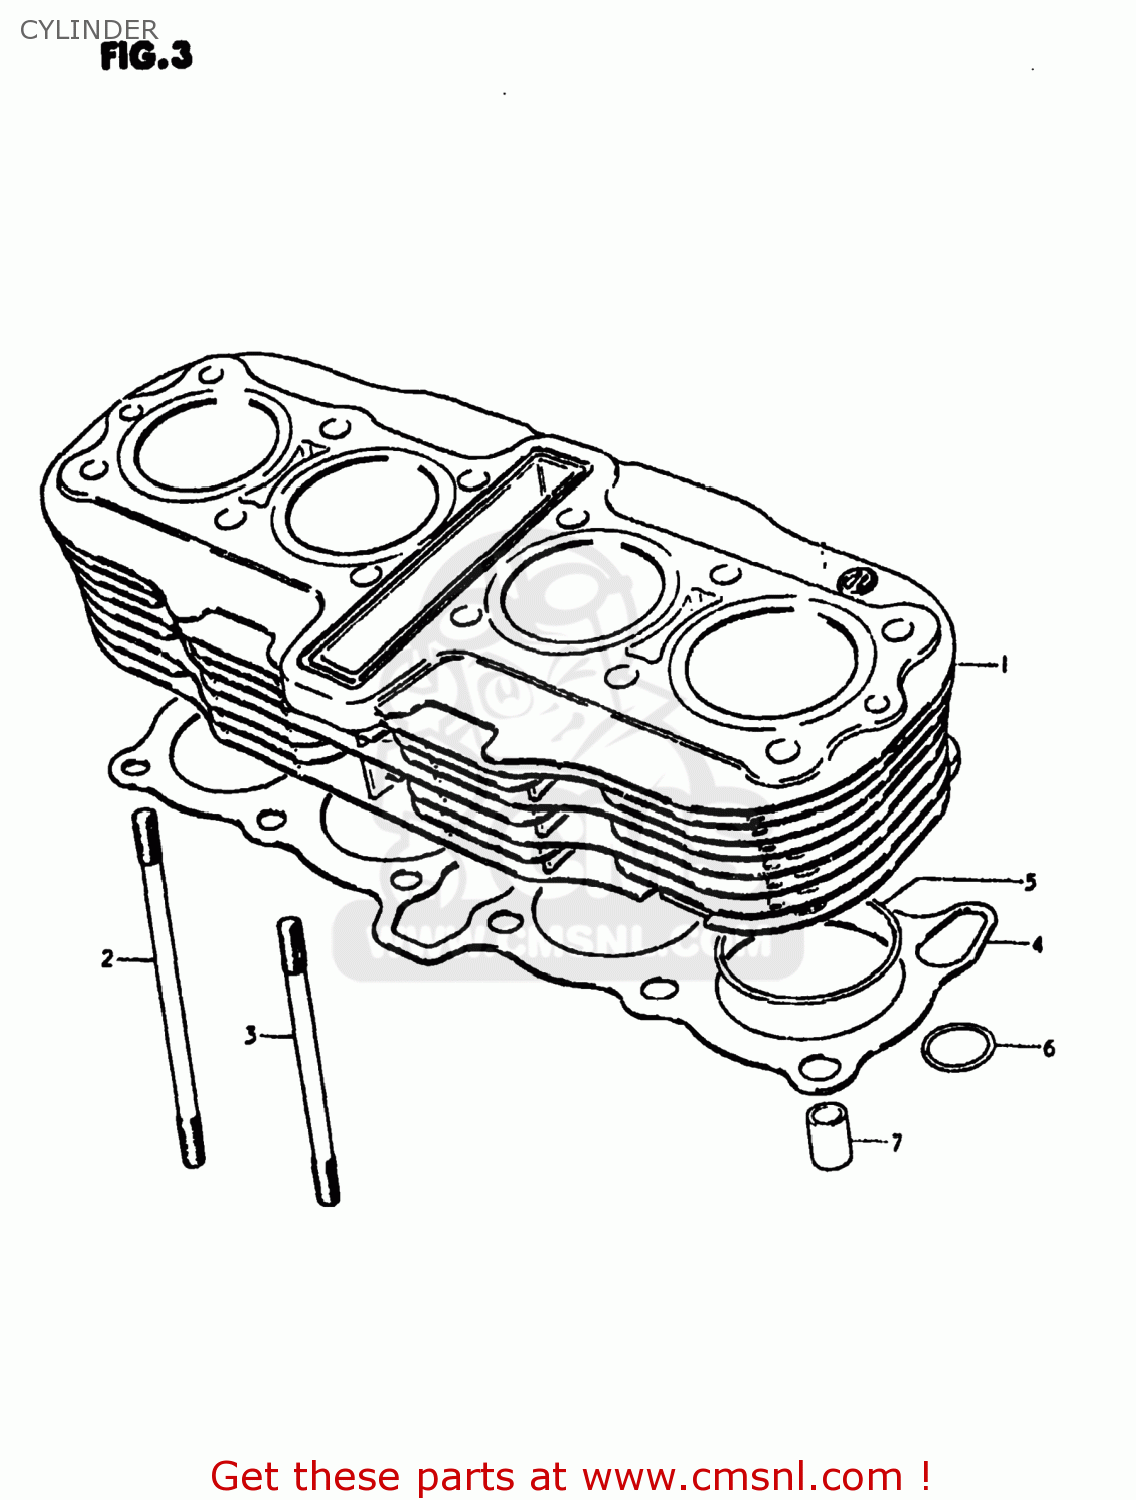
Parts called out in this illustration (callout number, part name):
1	CYLINDER
2	BOLT,STUD
3	STUD
4	GASKET,CYLINDER (MCA)
5	O RING(D:2,ID:74)
6	O RING(D:3.05)
7	PIN
